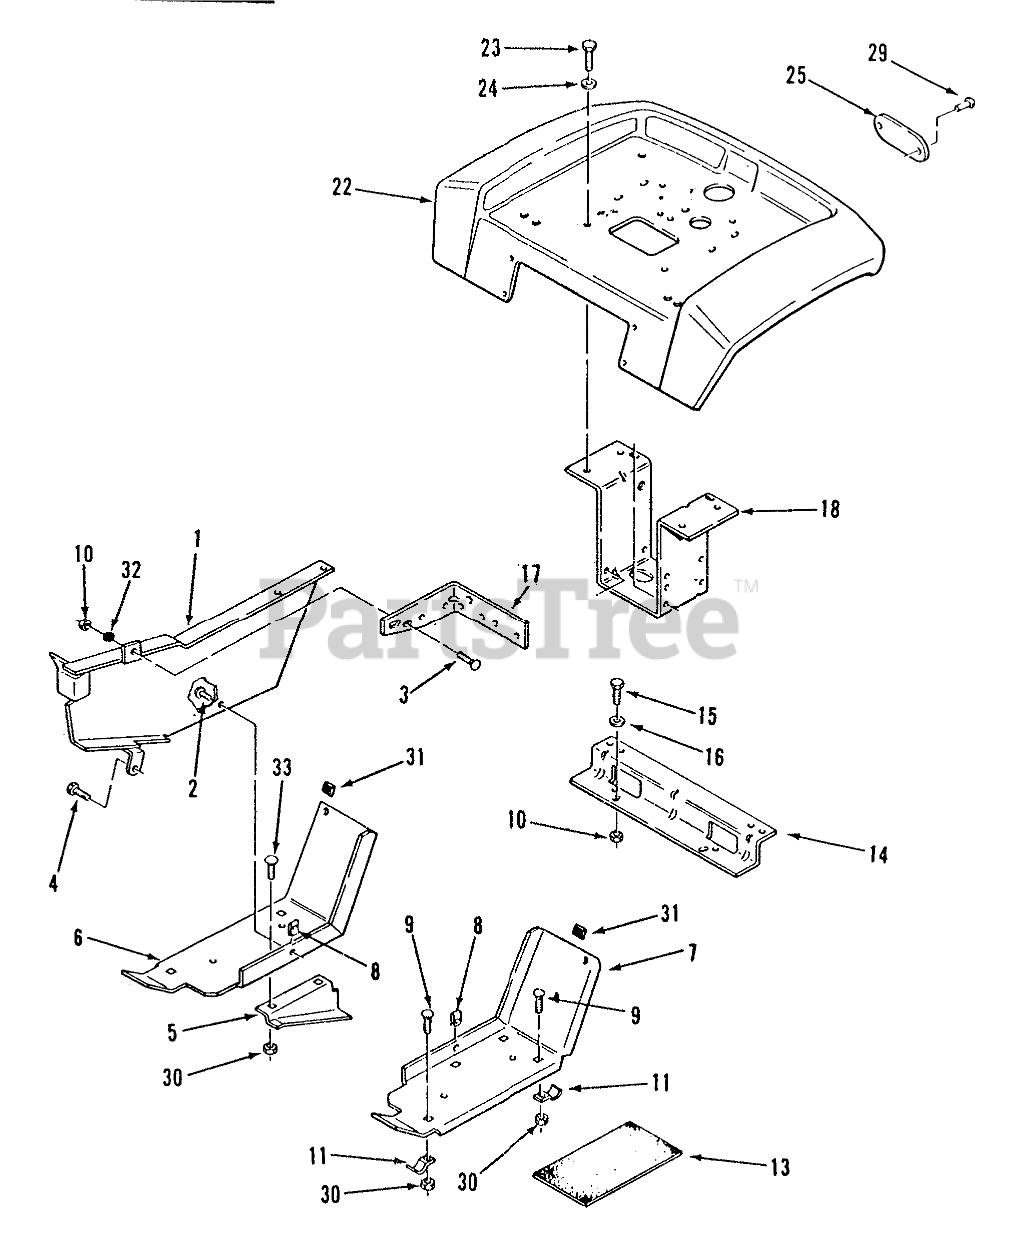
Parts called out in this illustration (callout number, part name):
1	Belt Guard
2	Screw
3	Bolt
4	SCREW
5	GUID-LOWER BLTR
6	Footrest-RH
7	FOOTREST LH R
9	Bolt
11	BRACKET
13	PAD-FOOTREST
14	BRACKET-FENDER B
15	Bolt
16	WASHER 5/16 SAE
17	SUPPORT-BELT GUAR B
18	Bracket-Fender Support
22	Fender
23	SCREW
24	WASHER 5/16 SAE
25	Reflector
29	Poprivet
30	Nut
31	BUMPER
32	NUT-PUSH
33	Bolt-Carriage
